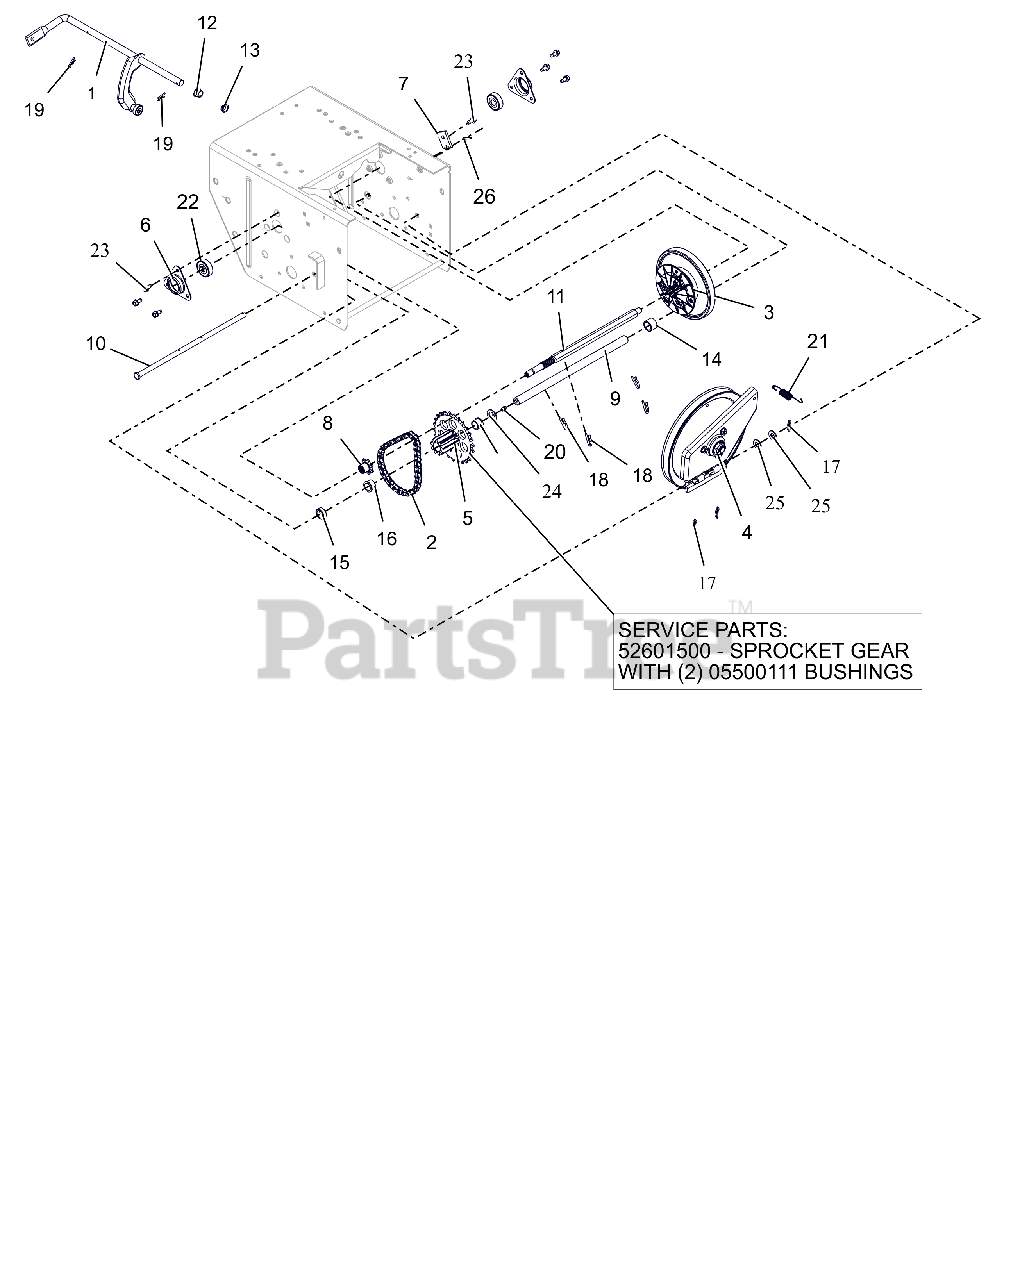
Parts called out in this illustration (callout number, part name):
1	ARM, SHIFT-PRO (ASSEMBLY)
2	CHAIN - #41, 32 PITCHES
3	DISC, FRICTION DRIVE-ASSEMBLY
4	PLATE, SWING ASSEMBLY-DEEP
5	PINION & SPROCKET
5	PINION & SPROCKET W/BUSHINGS
6	FLANGE, BEARING
7	TAB, ANTI ROTATION
8	SPROCKET, PINION 7T W/SPLINE
9	SHAFT, PINION - HARDENED
10	PIN, PIVOT
11	SHAFT, HEX - HEAT TREATED
12	BUSHING, POLYLINER-.50 SPLIT
13	BUSHING, POLYLINER-.50 SNAPIN
14	SPACER, .635X.880X.611
15	BSHG-SLV, .635X.880X.305
16	BSHG-FLG .625X.750X.500X.875
17	PIN, HAIR #225 .072X1.09
18	PIN, SPRING CLIP
19	CLIP, SPRING
20	ZERK,FITTING .25X.125 DRIVE IN
21	SG-TENS .048X.50X2.8
22	BRG-BALL .437X1.375X.437
23	SCR-TAP .25-20X.50 HWH ZCC
24	WSHR, FLT .630X1.005X.062 ZCC
25	WSHR,FLT .406X.812X.065 ZCC
26	PIN-ROLL .125X1.00
